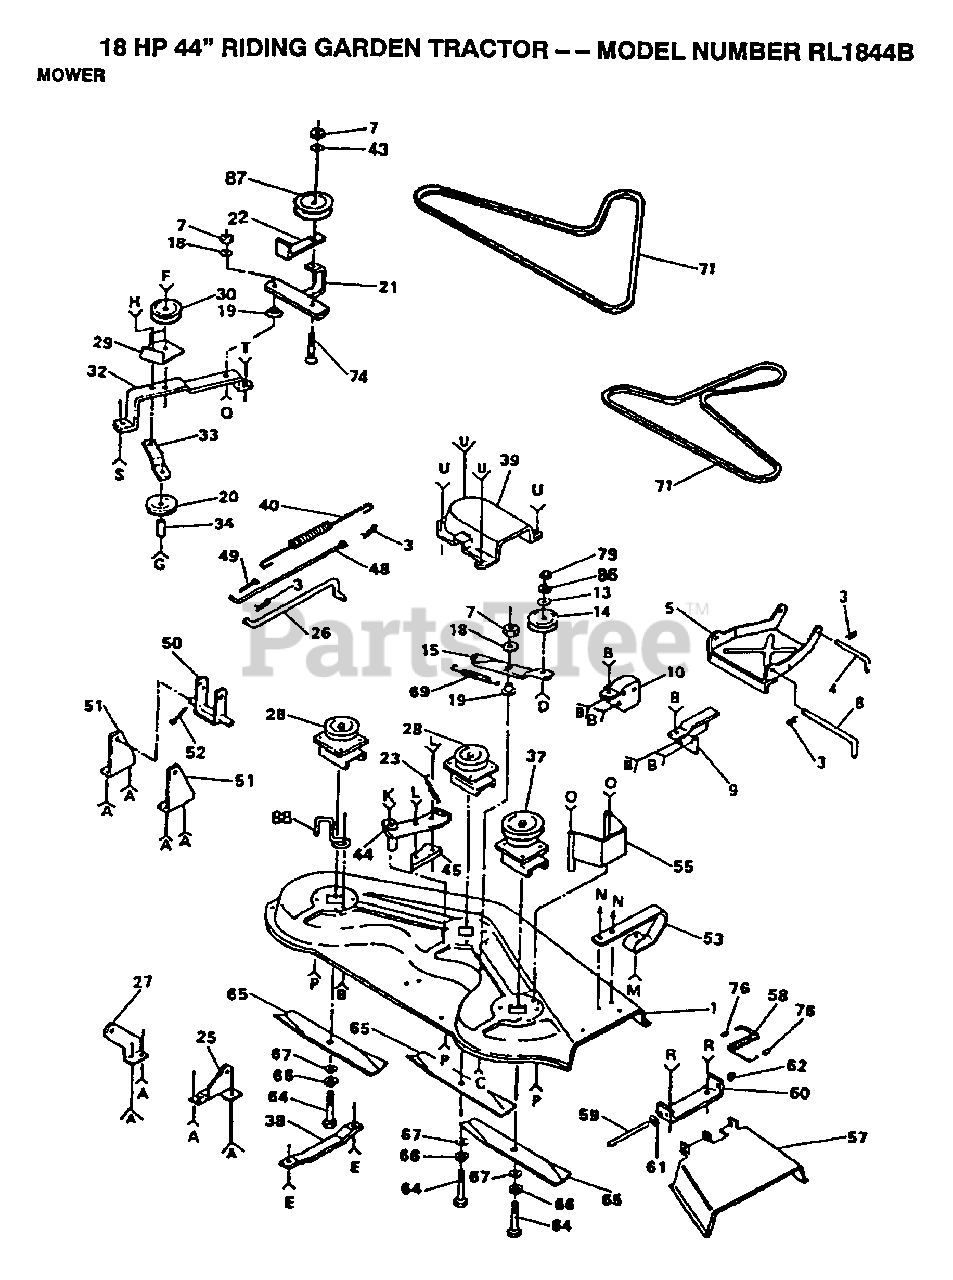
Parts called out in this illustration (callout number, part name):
2	LINK.PARALLEL
3	SPRING.RETAINER
4	"ROD, FRT. PARAL T"
5	LINK STOP
8	HINGE PIN T
9	BRACKET RH YT
10	BRACKET LH YT
11	BOLT
13	WASHER
14	IDLER.FLAT.GTV
15	ARM-IDLER YT
16	SCREW YT
18	"WASHER, WEAR LT"
19	SPACER RETAINER
20	IDLER-FLAT T
22	GUIDE BELT
23	SPRING-EXT YT
24	WASHER M
25	BRKT SUSP REAR RH
27	BRKT SUSP REAR LH
29	GUIDE-BELT YT
30	IDLER-INSIDE T
32	"SUPPORT YT, BAR"
33	BRACE-IDLER YT
34	SPACER
35	BOLT - HEX 3/8 - 16 X 3
38	RUNNER-LH M
39	GUARD YT
41	BOLT SHOULDER
42	LOCKNUT
43	WASHER
44	BRAKE ARM LT
45	BRAKE-BLOCK YTV
46	WASHER
48	ROD BRAKE YT
51	SUPPORT SHAFT YT
55	ASSY RH BELT GRD
56	BOLT
57	DEFLECTOR SHIELD
59	ROD-HINGE T
61	WASHER
62	NUT PUSH M
63	BOLT
64	BOLT.3/8-24X1-1/2
67	WASHER
68	SCREW
70	BOLT
71	BELT-V.79.1.MWR
74	BOLT
76	CAP-SLEEVE LT
77	BOLT
79	NUT.HEX.3/8-16UNC
80	NUT.HEX.5/16-18
81	LOCKWASHER
83	BOLT
86	LOCKWASHER
87	PULLEY IDLER
88	BELT RETIANER
89	WASHER
